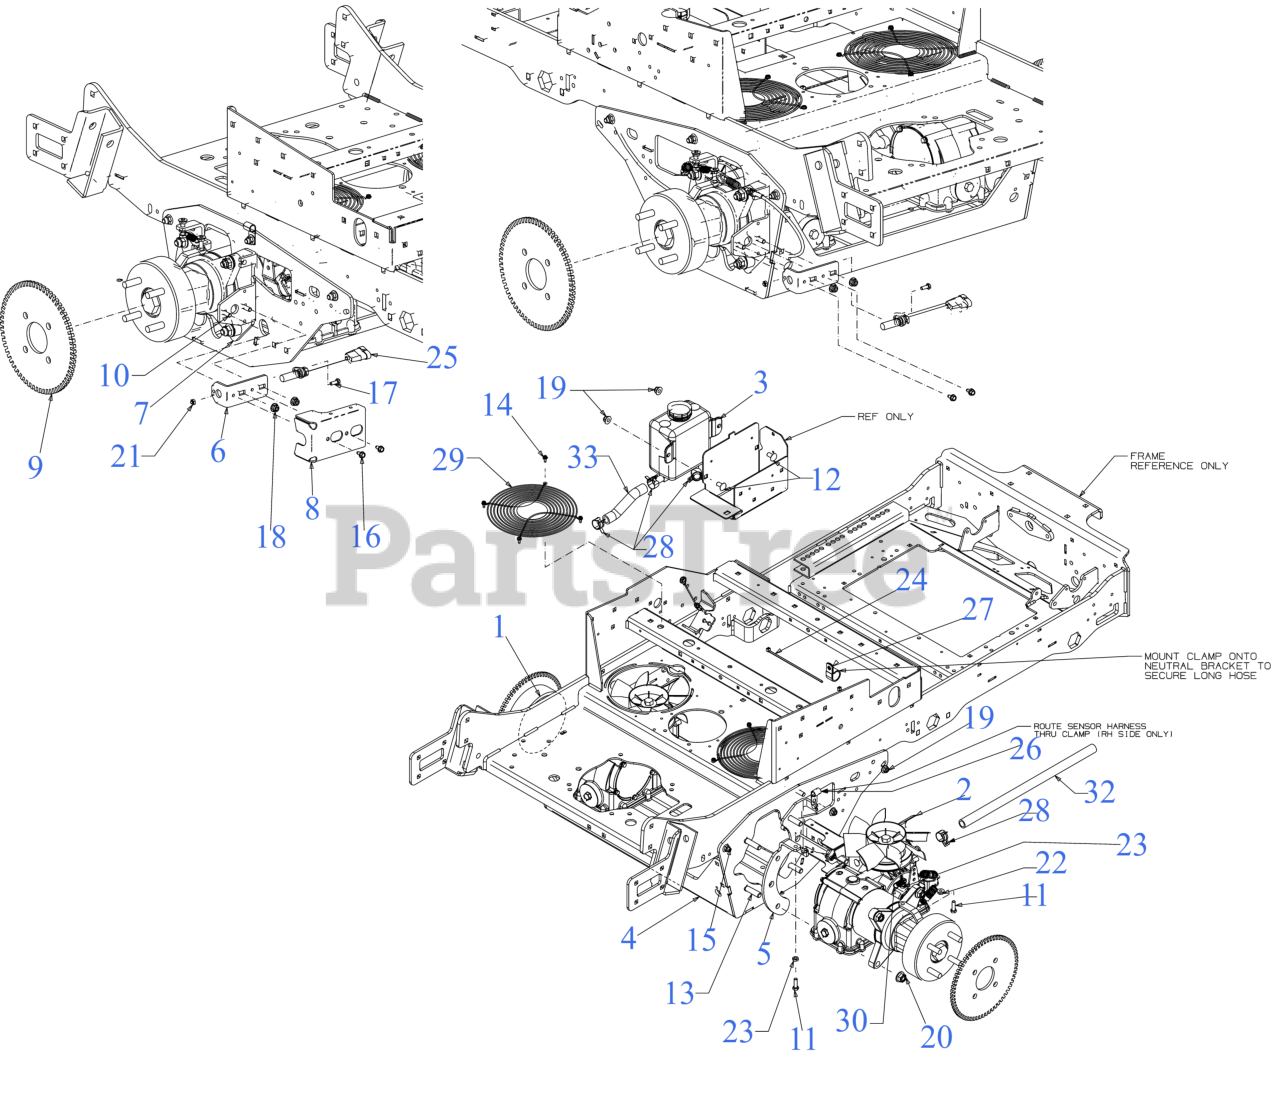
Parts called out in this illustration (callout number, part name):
1	TRANSMISSION ASSEMBLY PARKER (LH)
2	TRANSMISSION ASSEMBLY PARKER (RH)
3	HYDRO TANK ASSEMBLY
4	TRANSMISSION MOUNTING BRACKET
6	WHEEL SENSOR BRACKET
7	BRAKE SENSOR BRACKET
8	WHEEL SENSOR COVER BRACKET
9	WHEEL SENSOR SPACER
10	CARRIAGE BOLT 5/16-18 x 1.00
11	SCREW 5/16-18 x 1.0 GR5
12	CARRIAGE BOLT 3/8-16 x .750 GR5
13	CARRIAGE BOLT 1/2-13 GR5
14	SCREW 10-24 x 0.500
15	CARRIAGE BOLT 3/8-16 X1.25 GR5
16	SCREW 1/4-20 X.500
18	FLANGE LOCK NUT 5/16-18
22	HEX FLANGE NUT
24	7" CABLE TIE
25	WHEEL SPEED SENSOR
26	J TYPE CLIP
27	HOSE CLAMP 1.0"
28	HOSE CLAMP
30	EXTENSION SPRING .500 OD x 1.71
32	OIL HOSE 5/8 ID x 18.00 LG
